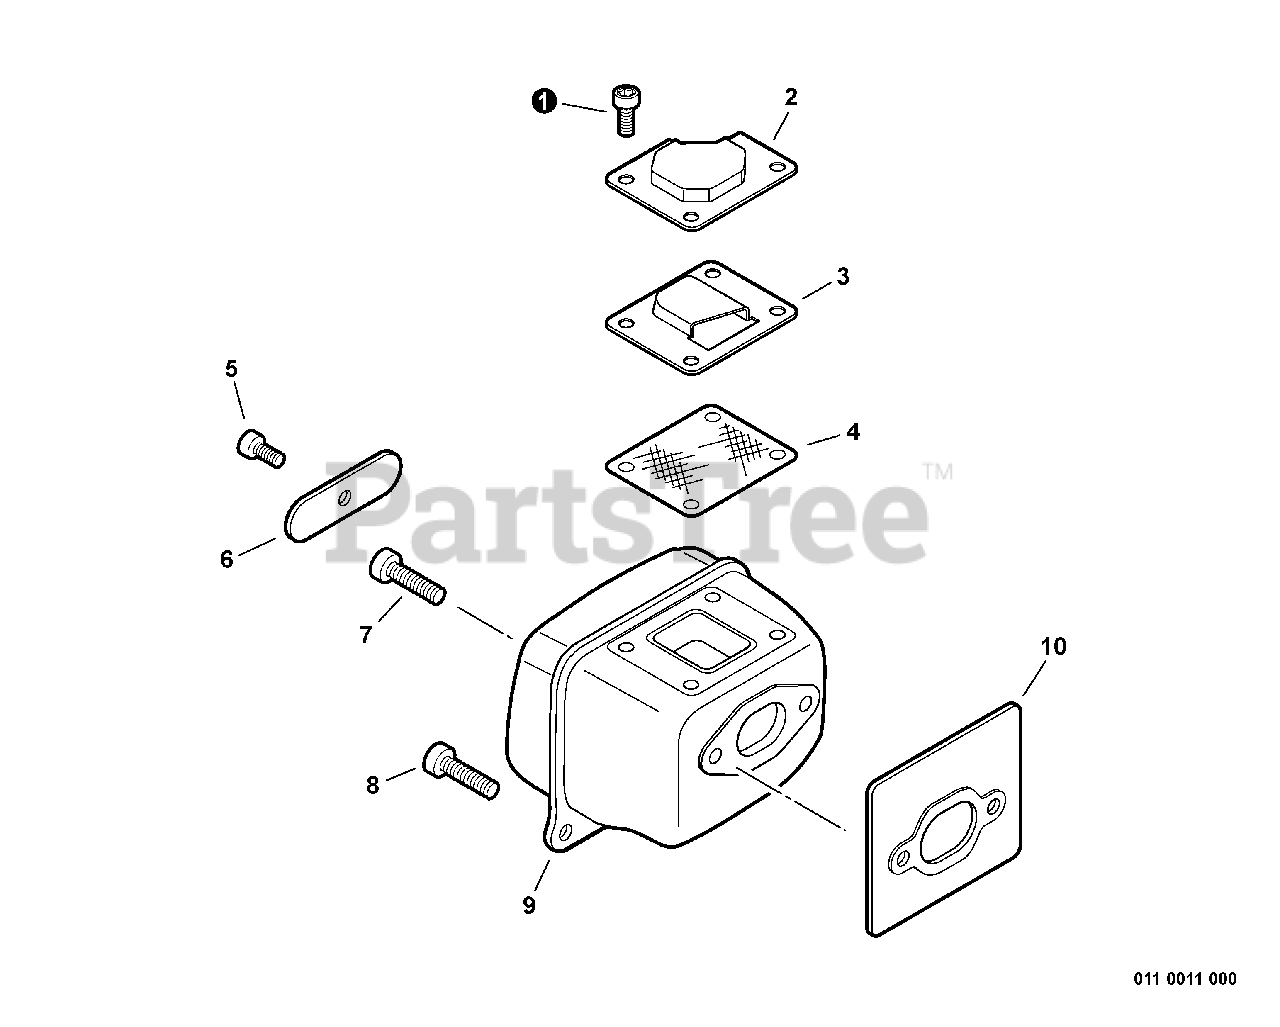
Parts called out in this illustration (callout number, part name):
1	SCREW - 4X8
2	GUIDE, EXHAUST - OUTER
3	GUIDE, EXHAUST - INNER
4	SCREEN, SPARK ARRESTOR
5	SCREW - 4X8
7	SCREW - 5X20
8	SCREW - 5X20
9	MUFFLER
10	GASKET, EXHAUST
